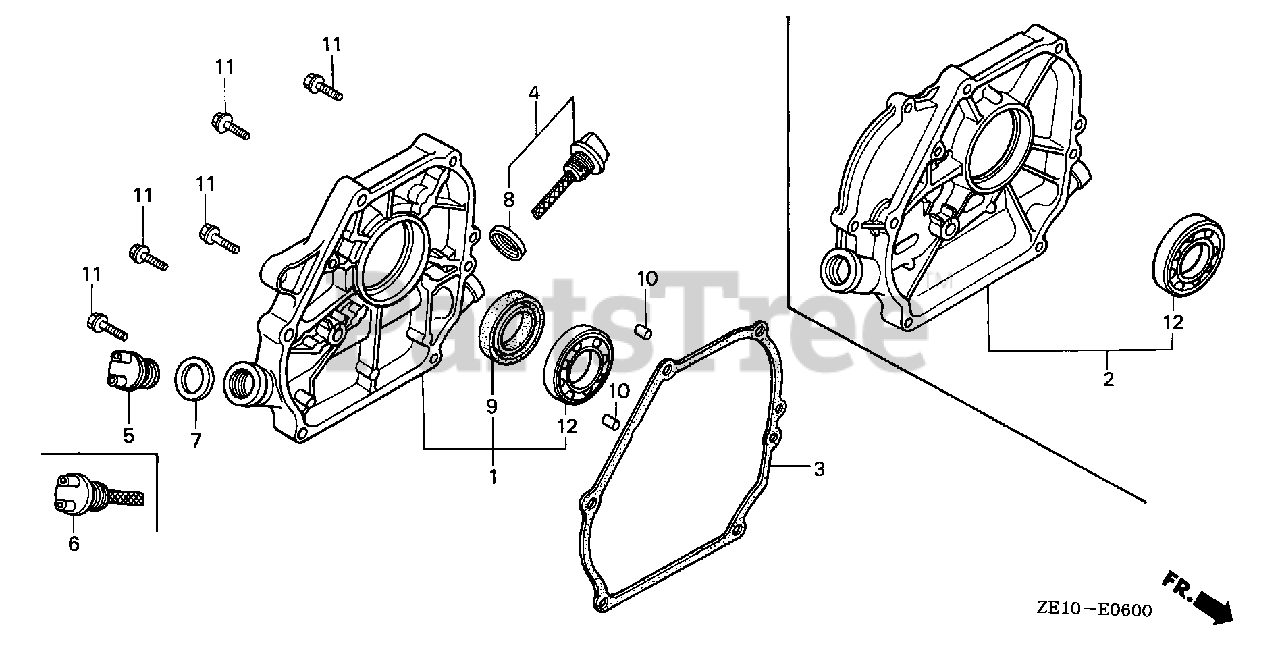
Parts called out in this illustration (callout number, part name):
1	COVER ASSY., CRANKCASE
3	GASKET, CASE COVER (NON-ASBESTOS)
4	CAP ASSY., OIL FILLER (GRAY)
5	CAP, OIL FILLER
6	CAP, OIL HOLE
7	GASKET, OIL FILLER CAP
8	GASKET, OIL FILLER CAP
9	OIL SEAL (25X41X6)
10	PIN, DOWEL (8X14)
11	BOLT, FLANGE (8X32)
12	BEARING, RADIAL BALL (6205)
